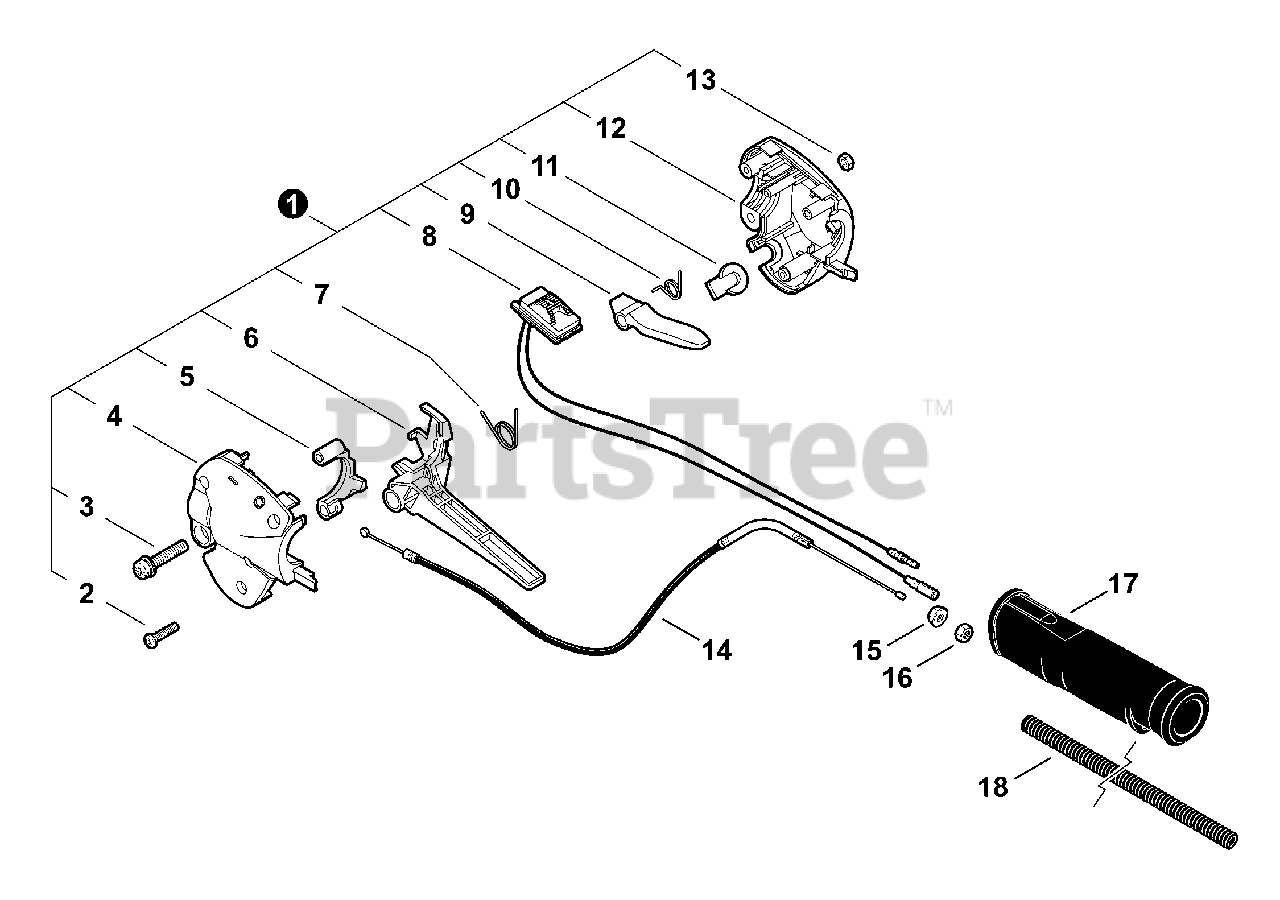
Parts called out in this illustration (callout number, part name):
1	CONTROL HANDLE KIT
2	SCREW - 4×20 -- TAPPING
3	SCREW - 5×16
4	HANDLE, CONTROL - LEFT
5	LOCKOUT, THROTTLE
6	TRIGGER, THROTTLE
7	SPRING, TRIGGER
8	SWITCH, IGNITION
9	LEVER, TRIGGER LOCKOUT
10	SPRING, LOCKOUT LEVER
12	HANDLE, CONTROL - RIGHT
14	CABLE, THROTTLE
15	NUT - 6 -- FLANGE
18	TUBE, PROTECTIVE - CORRUGATED
